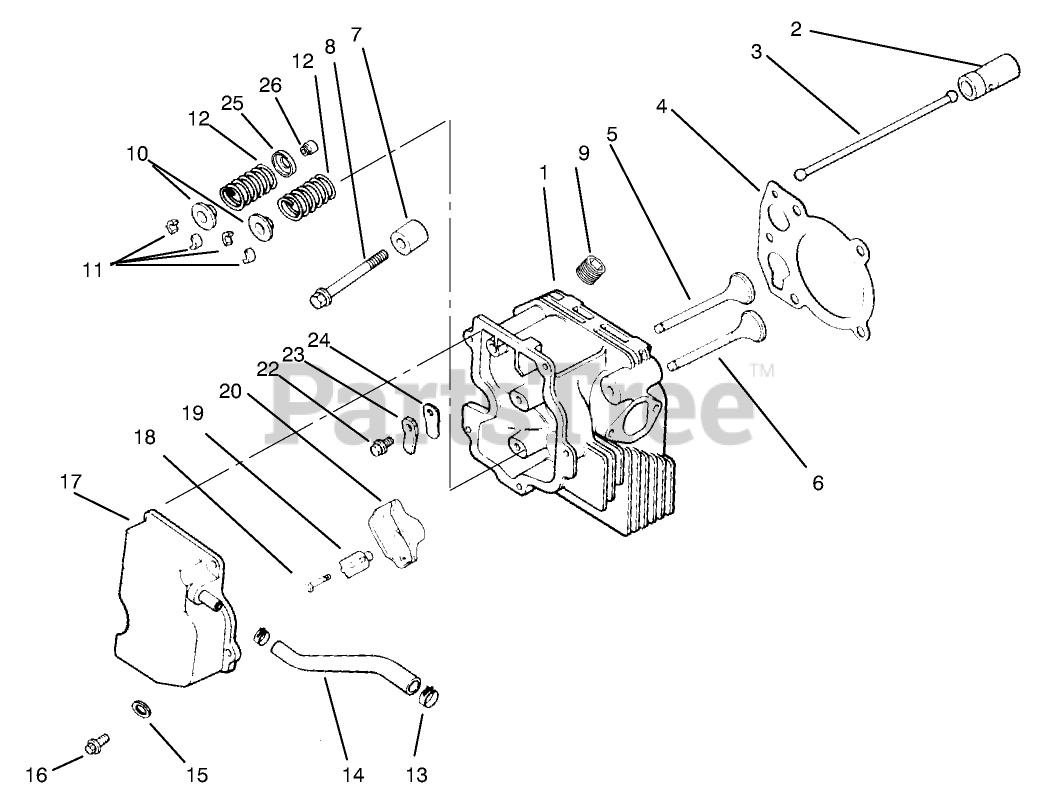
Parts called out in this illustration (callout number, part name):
1	Cylinder Head
2	Lifter-Valve
3	Rod-Push (Only On: 72042,72043,72062,72063)
4	Gasket-Cylinder Head (Only On: 72042, 72063, 72062, 72043)
4	Gasket-Cylinder Head
5	Valve-Intake STD (Only On: 72042, 72063, 72062, 72043)
5	Valve-Intake .25 (Only On: 72042,72043,72062,72063)
6	Valve-Exhaust STD (Only On: 72042,72043,72062,72063)
6	Valve-Exhaust .25 (Only On: 72042, 72063, 72062, 72043)
8	Spacer-Head Bolt Exhaust (Only On: 72042, 72063, 72062, 72043)
9	Screw M10x1.5x80 (Only On: 72042, 72063, 72062, 72043)
10	Cap-Valve Spring
11	Kit-Retainer
12	Spring-Valve Intake (Only On: 72042, 72063, 72062, 72043)
13	Clamp
14	Hose-Breather (Only On: 72042, 72063, 72062, 72043)
15	Washer-Flat (Only On: 72042, 72063, 72062, 72043)
17	Cover-Valve W/Nipple (Only On: 72042, 72063, 72062, 72043)
19	Pivot-Rocker Arm
20	Arm-Rocker
23	Retainer-Reed
24	Reed-Breather
25	Retainer-Spring
26	Seal-Valve Stem
